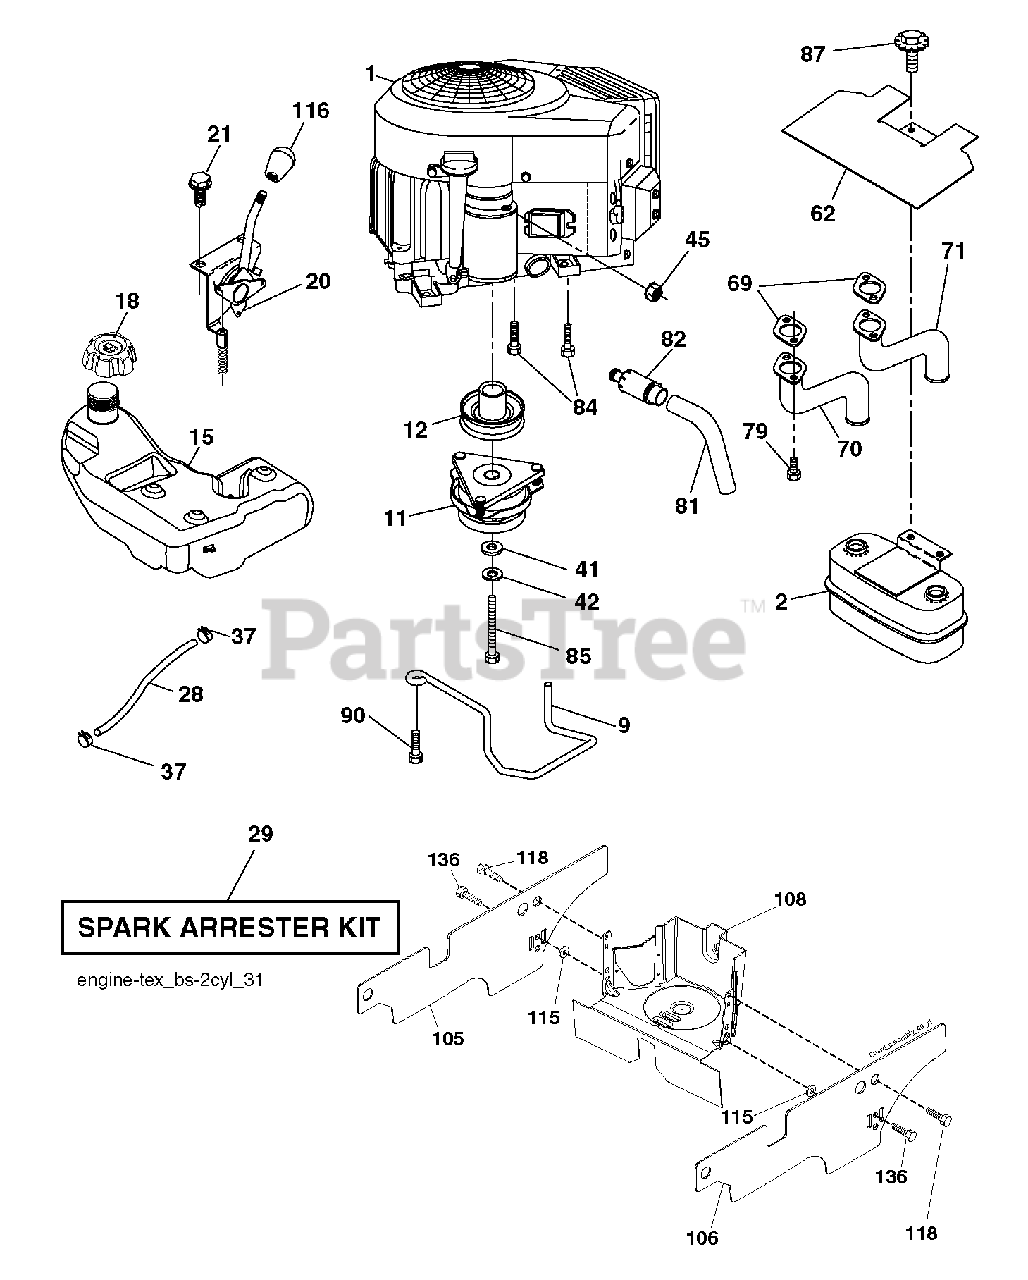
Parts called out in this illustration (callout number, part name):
2	MUFFLER.ASM.TWN.EXTNDED.DFLCTR
9	KEEPER BELT ENGINE
11	CLUTCH.ELECTRIC.LT.48"*
12	PULLEY.ENGINE.TUFFTORQ
15	TANK.FUEL.4GAL
18	CAP.FL.R.3'N/CARB.H.CROWN.498
20	CONTROL THROTTLE/CHOKE
21	SCREW.#10 X 0.750.BOS
28	REPL BY 532 00 85-43
29	KIT.SPARK ARRESTOR 794945 B&S
37	HOSE CLAMP
42	LOCKWASHER
45	NUT
62	SHIELD.HEAT.MUFFLER
69	GASKET.MUFFLER
70	EXHAUST.TUBE.LH.BS/TWIN
71	EXHAUST.TUBE.RH.B&S.TWIN.INTEK
79	SCREW.SOCKET.HEAD.5/16-18
81	TUBE, DRAIN OIL ASM.
82	VALUE.OIL.DRAIN
84	SCREW.3/8-16
85	BOLT HEX 7/16-20X4-1/4"
87	BOLT, 5/16-18 X 1 3/4
90	SCREW 3/8-16X1
105	SHIELD.SIDE.RH.3842"TEX FRENCH
106	SHIELD.SIDE.RH.46"FRENCH.TEX
108	COVER
115	PALNUT 1/4
116	KNOB - SHIFT
118	SCREW, 5/16-18 X 1/2
136	SCREW.1/4-20X5/8
